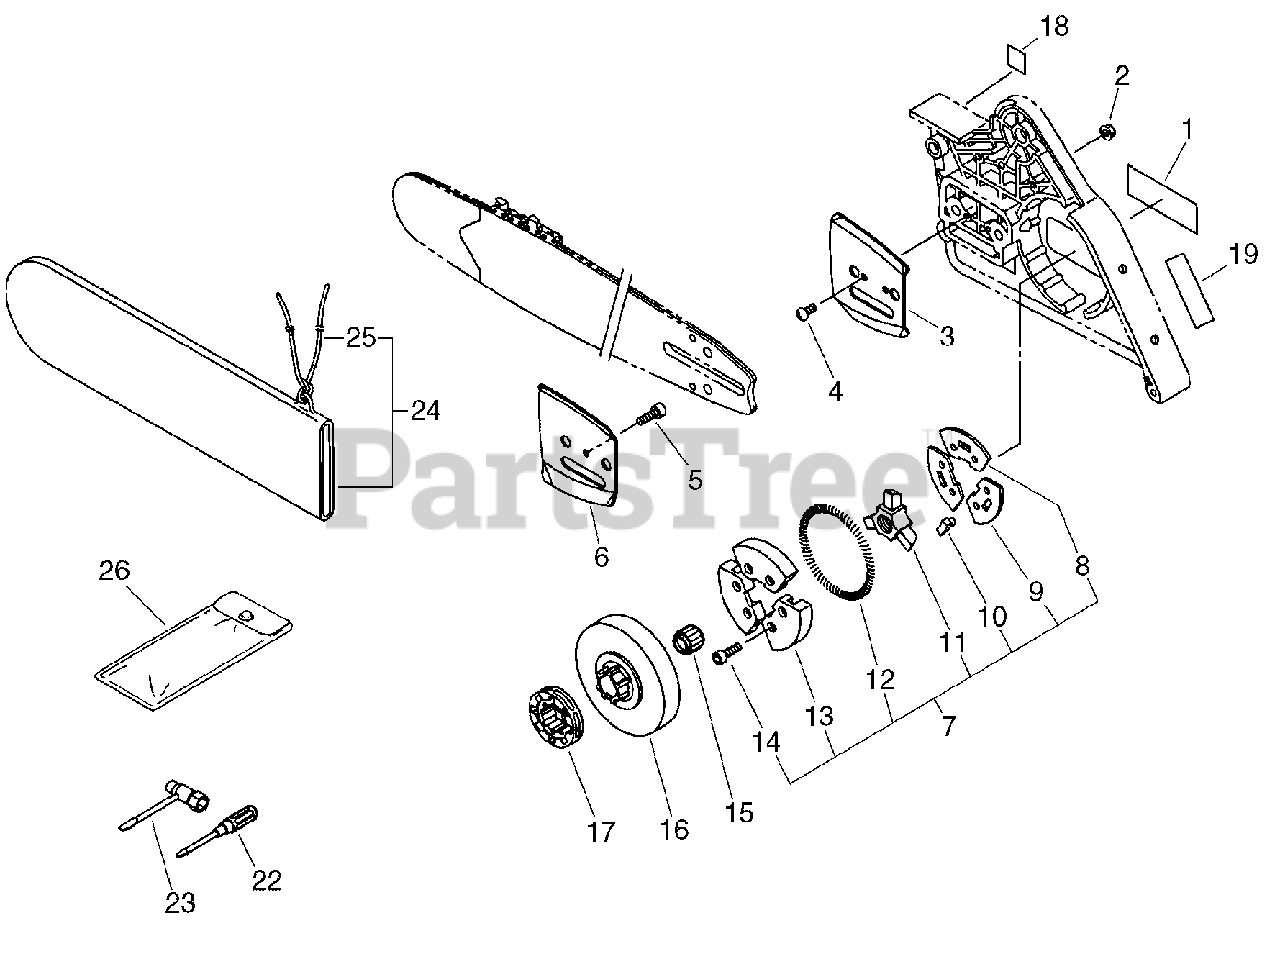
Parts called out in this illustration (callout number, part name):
1	LABEL, ECHO
2	NUT, FLANGE M8×1.25
3	PLATE, GUIDE - OUTER
4	SCREW 3×6
5	SCREW 4×8
6	PLATE, GUIDE - INNER
7	CLUTCH ASSY
8	PLATE, CLUTCH
9	PLATE, CLUTCH
11	HUB, CLUTCH
12	SPRING, CLUTCH
13	SHOE SET, CLUTCH
14	BOLT 4×8
15	BEARING, NEEDLE
16	DRUM, CLUTCH
17	SPROCKET, RIM 3/8"×7T
18	LABEL, CHAIN BRAKE
19	LABEL, CAUTION
22	SCREWDRIVER, PHILLIPS
23	T-WRENCH 13×19×180
24	SCABBARD
25	ROPE 5×900
26	BAG, TOOL
